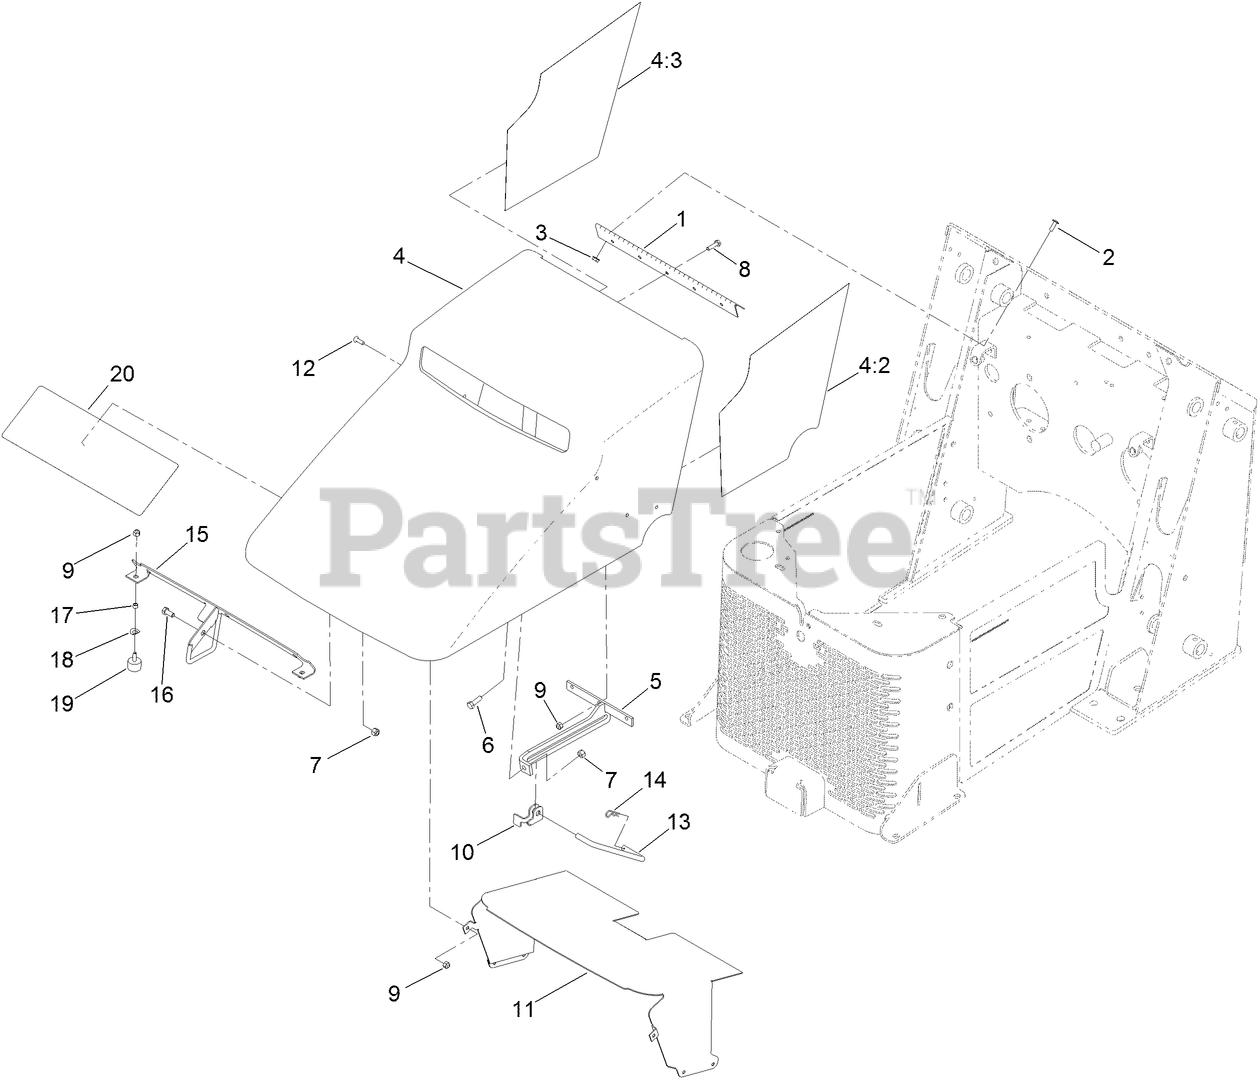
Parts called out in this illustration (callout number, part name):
1	HINGE-HOOD
2	SCREW-HEAD, TRUSS
3	NUT-HF
4:2	FOILTAPE-LH
4:3	FOILTAPE-RH
5	BRACKET-ROD, PROP
6	SCREW-HH
7	NUT-LOCK, NI
8	SCREW-HH
9	NUT-LOCK, NI
10	BRACKET-LATCH, LOCKING
11	BAFFLE-HOOD
12	SCREW-PRH
13	ROD-SUPPORT, HOOD
14	PIN-COTTER
15	ROD LATCH ASM
16	SCREW-HH
17	SPACER
18	WASHER-SPRING
19	BUMPER
20	DECAL-SERVICE
20	DECAL-SERVICE, FRENCH
20	DECAL-SERVICE, GERMAN
20	DECAL-SERVICE, SPANISH
20	DECAL-SERVICE, ITALIAN
20	DECAL- SERVICE, DUTCH
20	DECAL-SERVICE, POLISH
20	DECAL-SERVICE, RUSSIAN
20	DECAL-SERVICE, SLOVAKIAN
